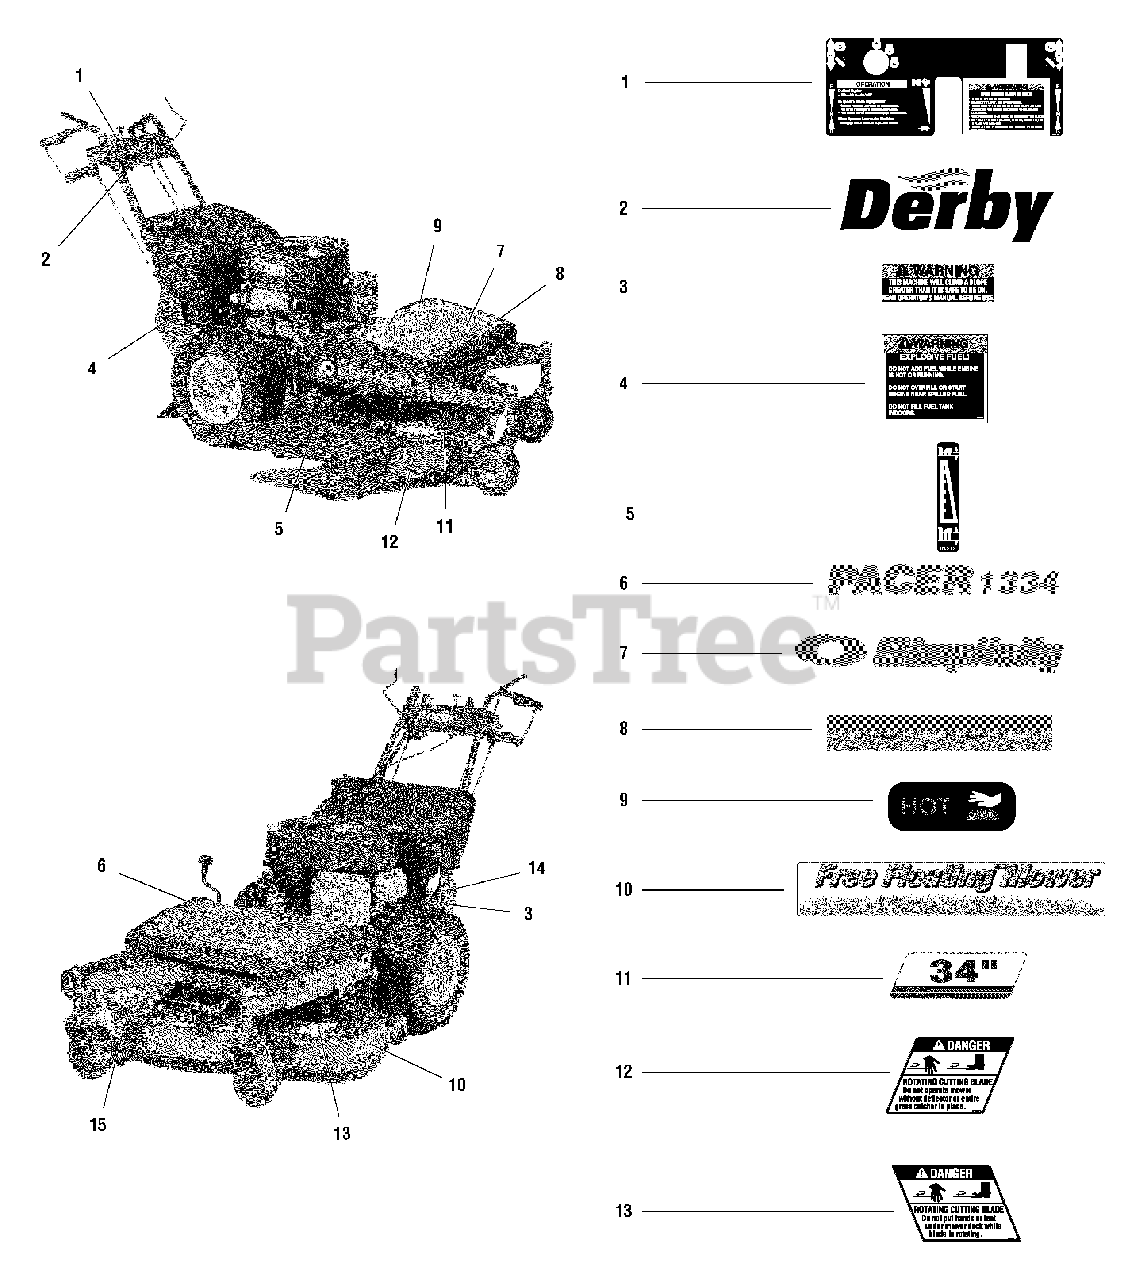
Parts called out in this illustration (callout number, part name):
1	DECAL, Control Panel
2	DECAL, Derby Logo
3	DECAL, Warning Machine Climb
4	DECAL, Warning Explosive Fuel
5	DECAL, Height Of Cut
6	DECAL, Pacer 1334
7	DECAL, Simplicity, Silver & Blue, W/Icon
8	DECAL, Stripe, Blue & Silver
10	DECAL, Free Floating
12	DECAL, Danger (Chute In Place)
13	DECAL, Danger (Hand Under Deck)
14	MODEL/SERIAL TAG (Not Serviced)
15	DECAL, OPEI (Not Serviced)
